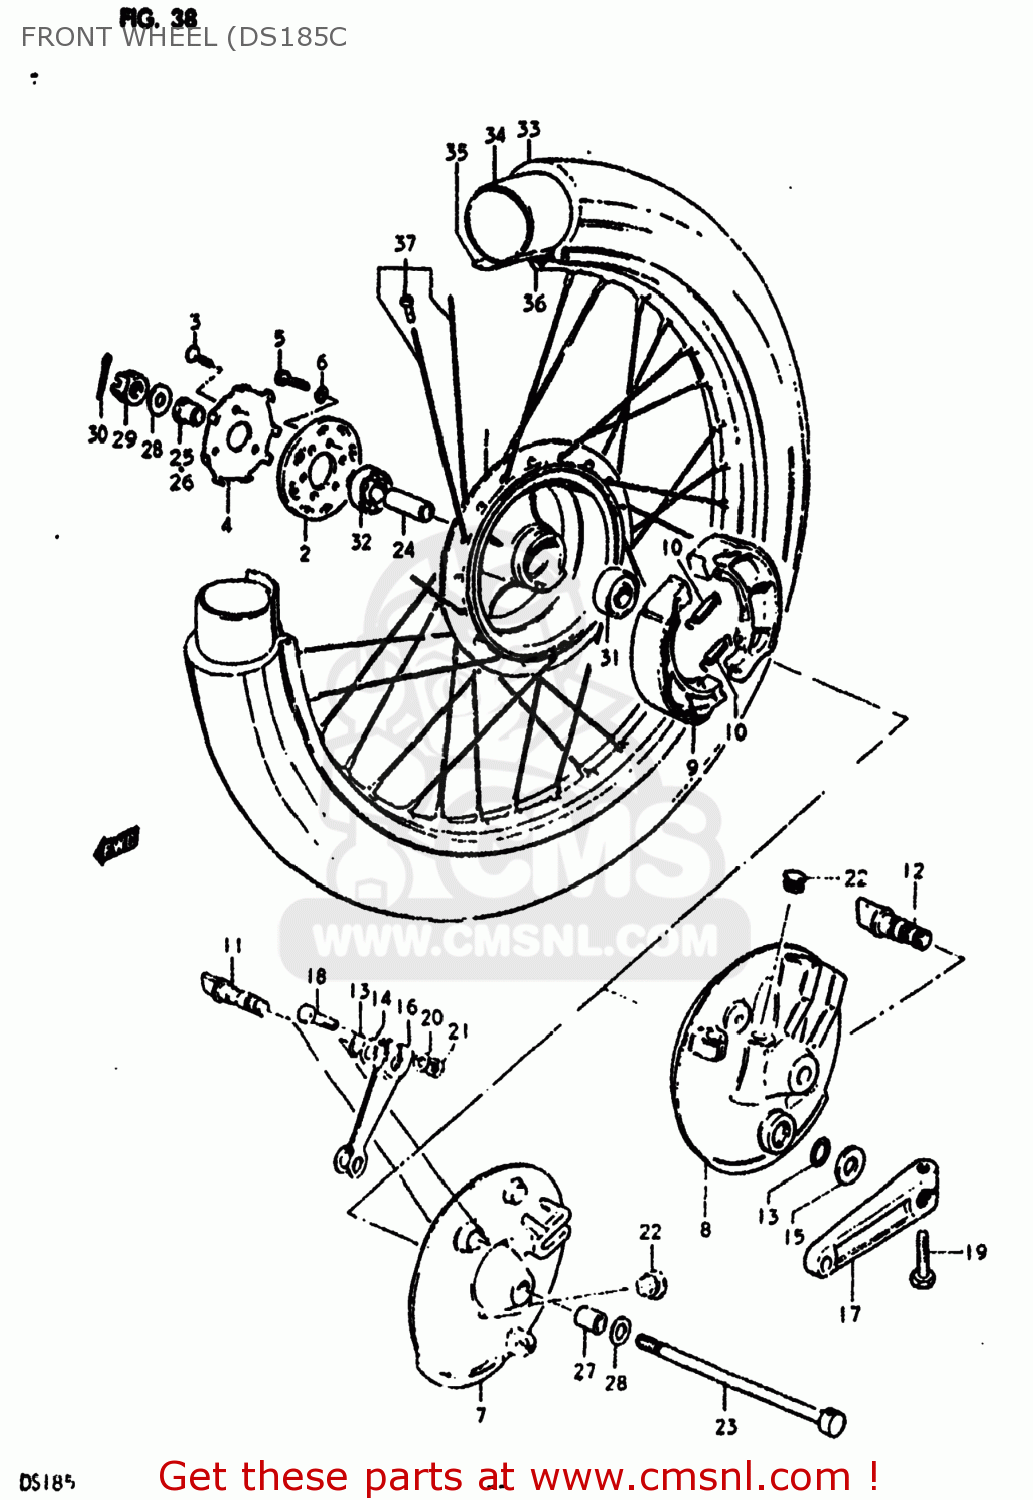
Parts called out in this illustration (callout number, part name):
1	HUB,FR WHEEL
2	FLANGE,FR HUB,R
3	SCREW
4	RETAINER,FR HUB BEARING,R
5	BOLT, UPPER
6	LOCK WASHER
7	PANEL,FRONT HUB
8	PANEL,FRONT HUB
9	SHOE,BRAKE
10	SPRING(L:34)
11	CAM,FRONT BRAKE
12	CAM,FRONT BRAKE
13	O RING(D:2.5,ID:11.4)
14	WASHER (14.5X22X1.6)
15	WASHER(12.5X20X1)
16	LEVER,FR BRAKE CAM
17	LEVER,FRONT BRAKE CAM
18	BOLT(6X33)
19	BOLT
20	WASHER
21	NUT
22	CAP(OD:17)
23	AXLE,REAR
24	SPACER (12.6X19X52)
25	SPACER (12.2X19X18.5)
26	SPACER,FR AXLE,R
27	SPACER(12X20X34.5)
28	WASHER
29	NUT 12MM
30	COTTER PIN
31	BEARING
32	BEARING, RH
33	TIRE,FRONT
34	TUBE
35	PROTECTOR,WHEEL,INNER
36	RIM,FRONT WHEEL
37	SPOKE SET,FRONT
